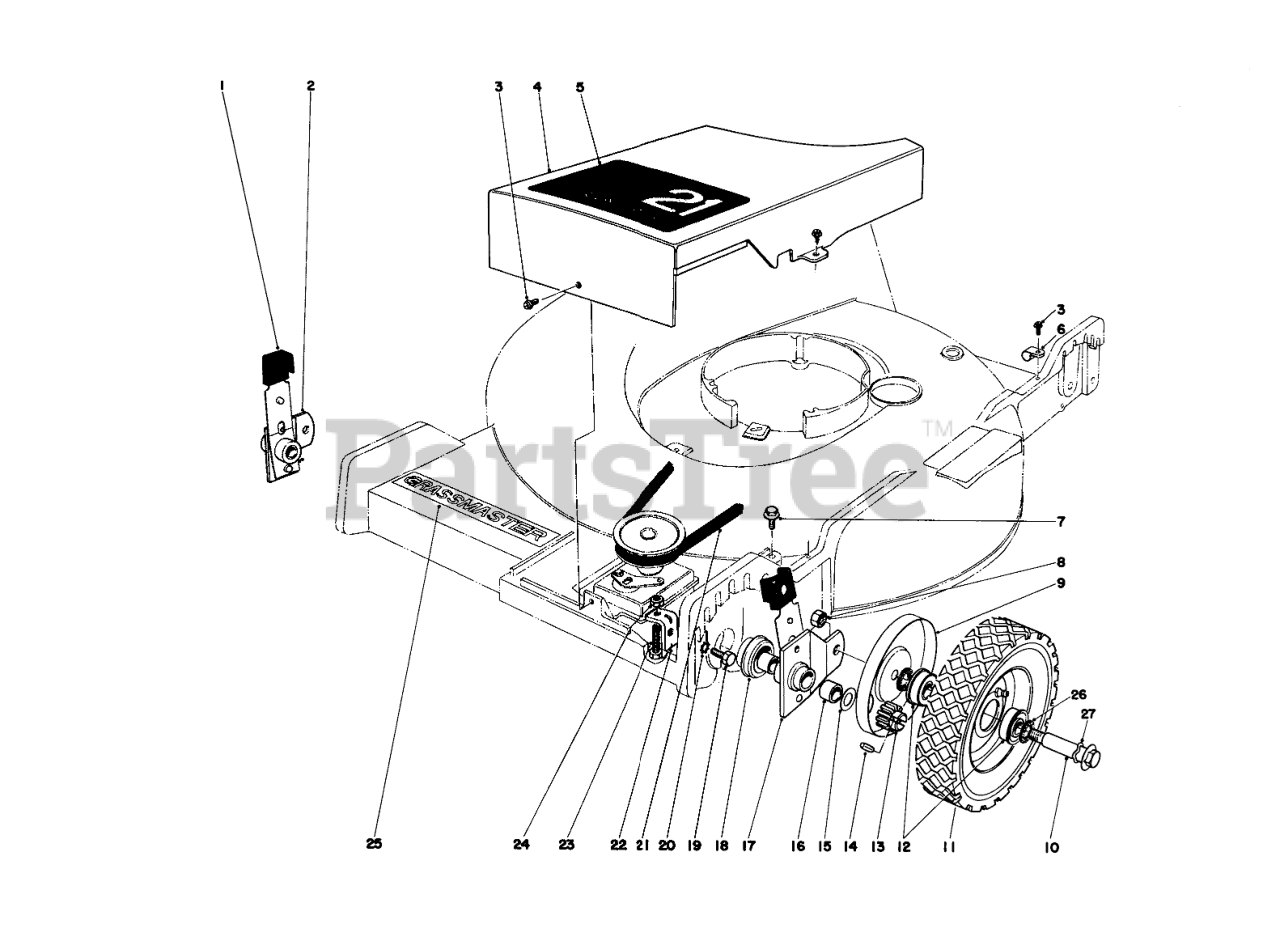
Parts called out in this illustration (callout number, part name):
1	KNOB-ARM
2	Pivot Arm (Incl. Ref. #16)
3	SCREW
4	Belt Cover
5	Decal Belt Cover
6	CLAMP-NYLON
7	SCREW-HWHTF
8	Nut
9	WHEEL COVER
10	WHEEL BOLT
11	Wheel & Tire Assembly Front (Incl. Ref. #12)
12	BEARING-BALL
13	Pinion
14	PIN-GROOVED
15	WASHER-THRUST
16	BUSHING
17	Pivot Arm (Incl. Ref. #16)
18	End Cap
19	SCREW-HH
20	WASHER-LOCK
21	V-BELT
22	Bracket-Gear Box
23	SCREW
24	NUT-LOCK
25	Decal Grassmaster
26	FELT WASHER
27	SPRING WASHER
